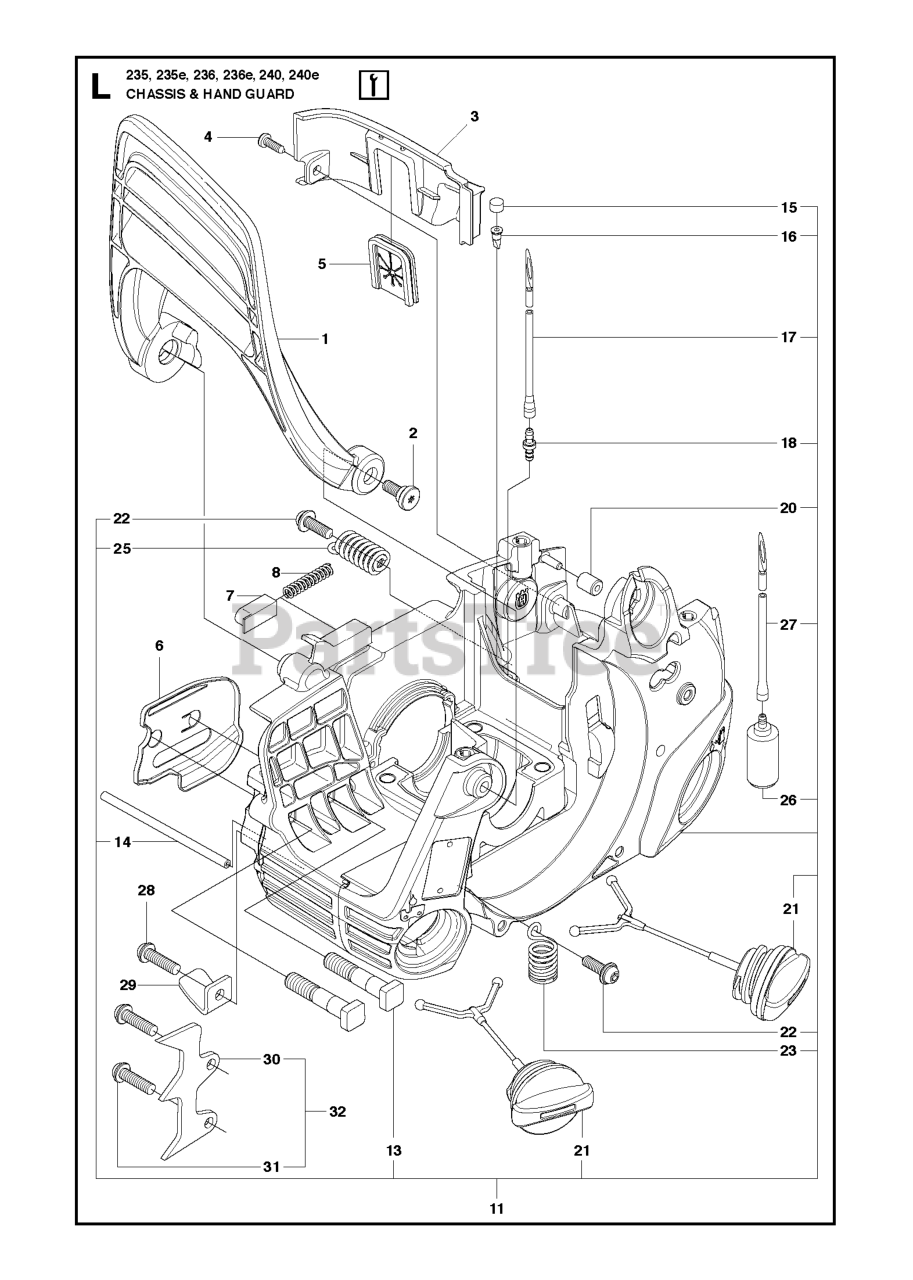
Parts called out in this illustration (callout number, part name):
1	HAND GUARD HHS
2	BOSS SCREW
4	SCREW 6-19X.437
7	CAP, SPRING HANDGUARD
11	HHS CHASSIS ASSEMBLY
13	BOLT
15	VENT,FUEL TANK 36/41
16	VALVE-CHECK (DUCKBILL)
17	LINE KIT
18	FUEL LINE FITTING
20	ISOLATOR FILTER HOUSING
21	TANK CAP ASSY
22	SCREW,FRONT HBAR 36/41
26	ASSY FUEL PICKUP PRE FLUSHED
27	LINE FUEL LOW PERM
29	CHAIN CATCHER 36/41
30	SPIKE
32	SPIKE 36/41
